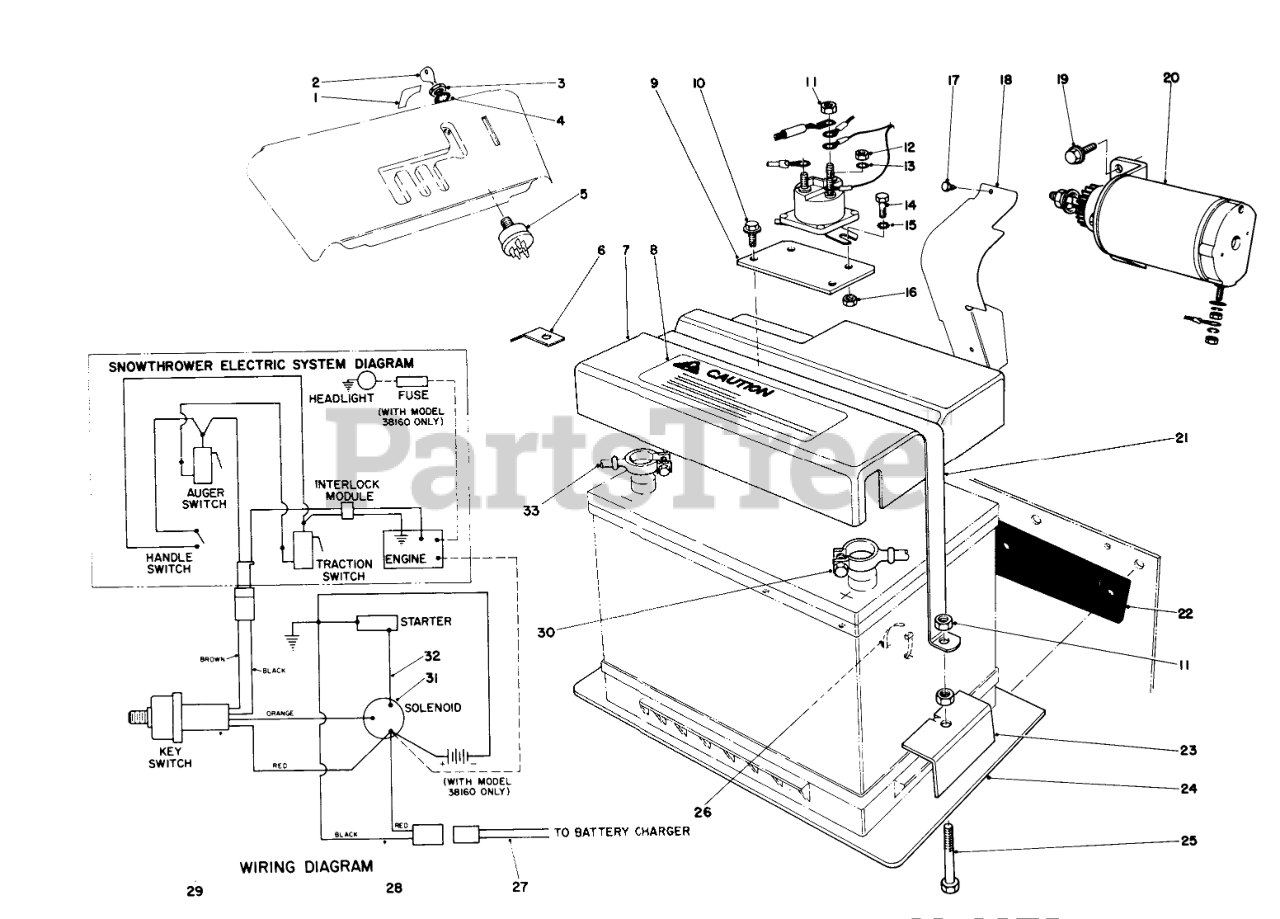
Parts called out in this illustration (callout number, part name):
1	Decal Switch
2	Key
4	WASHER-TOOTH, INTERNAL
5	Smarter Switch
6	Bracken Wire Clamp
7	BATTERY COVER & DECAL
8	Decal-Caution
9	Bracket Solenoid
10	SCREW-HWH
11	NUT-HEX
12	NUT-HEX
13	WASHER-LOCK, INT
14	SCREW-HH
15	WASHER-LOCK/EXT
16	NUT-LOCK, NI
17	Hex Hd. Sems Screw
18	Pinion Shield
19	Screw-HH
20	Starter Motor & Pinion Assy.
21	Strap Battery
22	Batery Isolation Pad
23	BATTERY CLAMP
24	Battery Mounting Plate
25	SCREW-HH
26	TIE-CABLE
27	MALE WIRE ASM
28	FEMALE WIRE ASM
29	Wire Harness
30	BATT-SOLENOID CABLE
31	SOLENOID
32	STRT MTR-SOLNOID WIRE
33	BATT-GROUND CABLE
